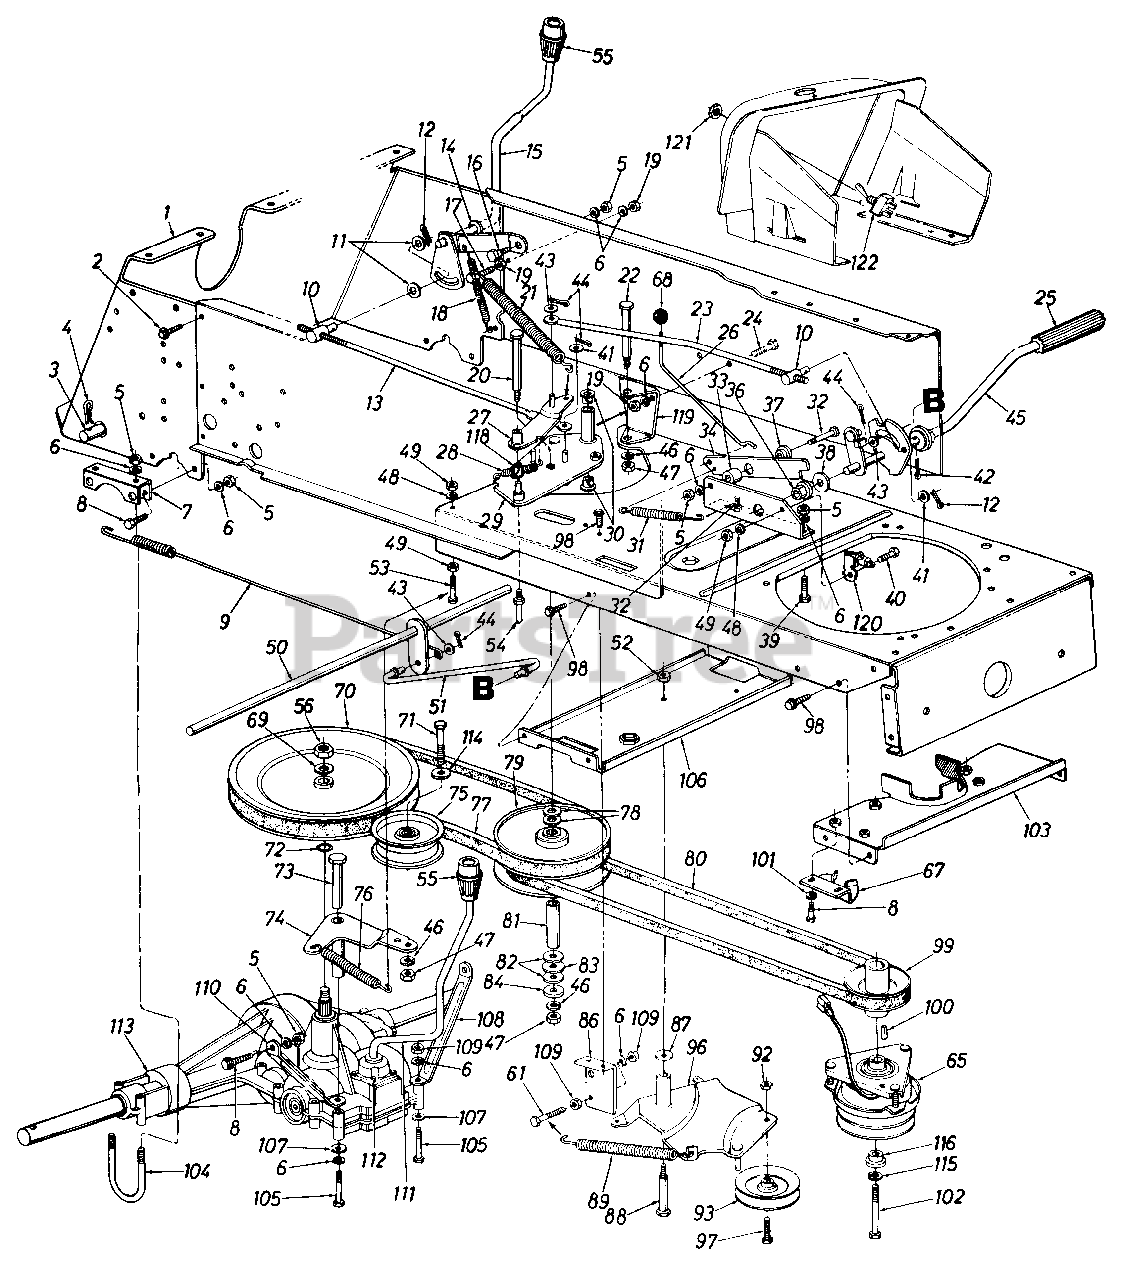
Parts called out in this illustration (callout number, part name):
3	Hitch Rod
4	Hitch Pin Clip
5	Hex Nut 5/16-18 Thd.
6	L-Wash. 5/16" I.D.
7	Transaxle Bracket
8	Hex Bolt 5/16-18 x .75" Lg. (Gr. 5)
9	Brake Extension Spring
10	Adjustment Ferrule 3/8-24 Thd.
11	Fl-Wash. .385" I.D. x .87"
12	Internal Cotter Pin
13	Speed Control Link
14	Fl-Wash. .531" I.D. x .94"
15	Speed Selector Lever Assly.
16	Shld. Bolt .437" Dia. x .162"
17	Hex Bolt 5/16-24 x 1.25" Lg.
18	Extension Spring 3.9" Lg.
19	Hex Nut 5/16-24 Thd. (Gr. 5)
20	Hex Bolt 3/8-24 x 4.5" Lg.
21	Extension Spring 11" Lg.
22	Shld. Bolt .625" Dia. x 3.5" Lg.
23	Speed Control Link
24	Hex Bolt 5/16-24 x .75" Lg.
25	Foot Pad
26	Parking Brake Link
27	Variable Speed Torque Brkt. Ass'y.
28	Extension Spring 2.59" Lg.
29	Pulley Brkt. Sub Ass'y.
30	Flanged Brg. .625" I.D.
31	Extension Spring 2.51" Lg.
32	Hex Bolt 5/16-18 x 1.25" Lg.
33	Spacer .34" I.D. x .88"
36	Hex Flange Brg. .634" I.D.
37	Shld. Spacer .5" Dia.
38	Fl-Wash. .64" I.D. x 1.24"
39	Hex Bolt 5/16-18 x .75" Lg.
40	Hex Bolt 1/4-20 x .62" Lg.
41	Fl-Wash. .406" I.D. x .75" O.D.
42	Cotter Pin 118" Dia.
43	Fl-Wash. .34" I.D. x .68" O.D.
44	Cotter Pin 3/32" Dia.
45	Foot Pedal Brkt. Ass'y.
46	L-Wash. 3/8" I.D.
47	Hex Nut 3/8-24 Thd.
48	L-Wash. 1/4" I.D.
49	Hex Nut 1/4-20 Thd.
50	Brake Link Bracket
51	Front Brake Rod Link
52	Hex Cent. L-Nut 3/8-16 Thd.
53	Hex Bolt 1/4-20 x 2.0" Lg.
54	Belt Guard Pin
55	Shift Knob
56	Hex Jam Nut 9/16-18 Thd.
61	Hex Bolt 5/16-24 x 1.75" Lg.
65	Electric Clutch
69	Bell-Wash. 9/16" I.D. x 1.25"
70	V-Pulley 91/4" O.D.
71	Hex Bolt 3/8-24 x 1.75" Lg.
72	Wire Ring
73	Shld. Bolt 5/16-24 Thd.
74	Idler Brkt. Ass'y.
75	Flat Idler 3.5" O.D.
76	Extension Spring 6.12" Lg.
77	V-Belt
78	Teflon Washer 1.20" O.D.
79	Variable Speed Pulley 6" Dia.
80	V-Belt
81	Pivot Bushing
82	Fl-Wash. .56" I.D. x 1.0" O.D.
83	Thrust Brg. .56" I.D. x 1.25" O.D.
84	Retainer Cup
86	Parking Brake Mtg. Brkt.
87	Bell-Wash. .38" I.D. x .88" O.D.
88	Shld. Bolt .498" Dia. x 2.05"
89	Extension Spring 4.0" Lg.
92	Hex Cent. L-Nut 3/8-24 Thd.
93	V-Belt Idler
96	Idler Brkt. Deck Ass'y.
97	Hex Bolt 3/8-24 x 1.5" Lg.
98	Hex Wash. Hd. TT-Tap Scr. 1/4-20 x .5" Lg.
99	Engine Pulley
100	Sq. Key 1/4 x 1.5" Lg.
101	Bell-Wash. .345" I.D. x .88"
102	Hex Bolt 7/16-20 x 3.75" Lg.
103	Belt Keeper Brkt. Ass'y.
104	U-Bolt
105	Hex Bolt 5/16-24 x 2.25" Lg.
106	Deck Idler Support Brkt.
107	Fl-Wash. .344" I.D. x .62" O.D.
108	Front Transaxle Support Brkt. L.H.
109	Hex Nut 5/16-24 Thd.
110	Front Transaxle Support Brkt. R.H.
111	Shift Lever Ass'y. Complete
112	Socket Hd. Cap Scr. #10 x 24
113	2-Speed Transmission Comp.
114	Fl-Wash. 3/8" I.D. x 1.0" O.D.
115	L-Wash. 7/16" I.D.
116	Shld. Spacer
118	Nyliner Flanged Brg.
119	Variable Speed Support Brkt.
120	Safety Switch
121	Hex Nut 1/2-27 Thd.
122	Toggle Switch
